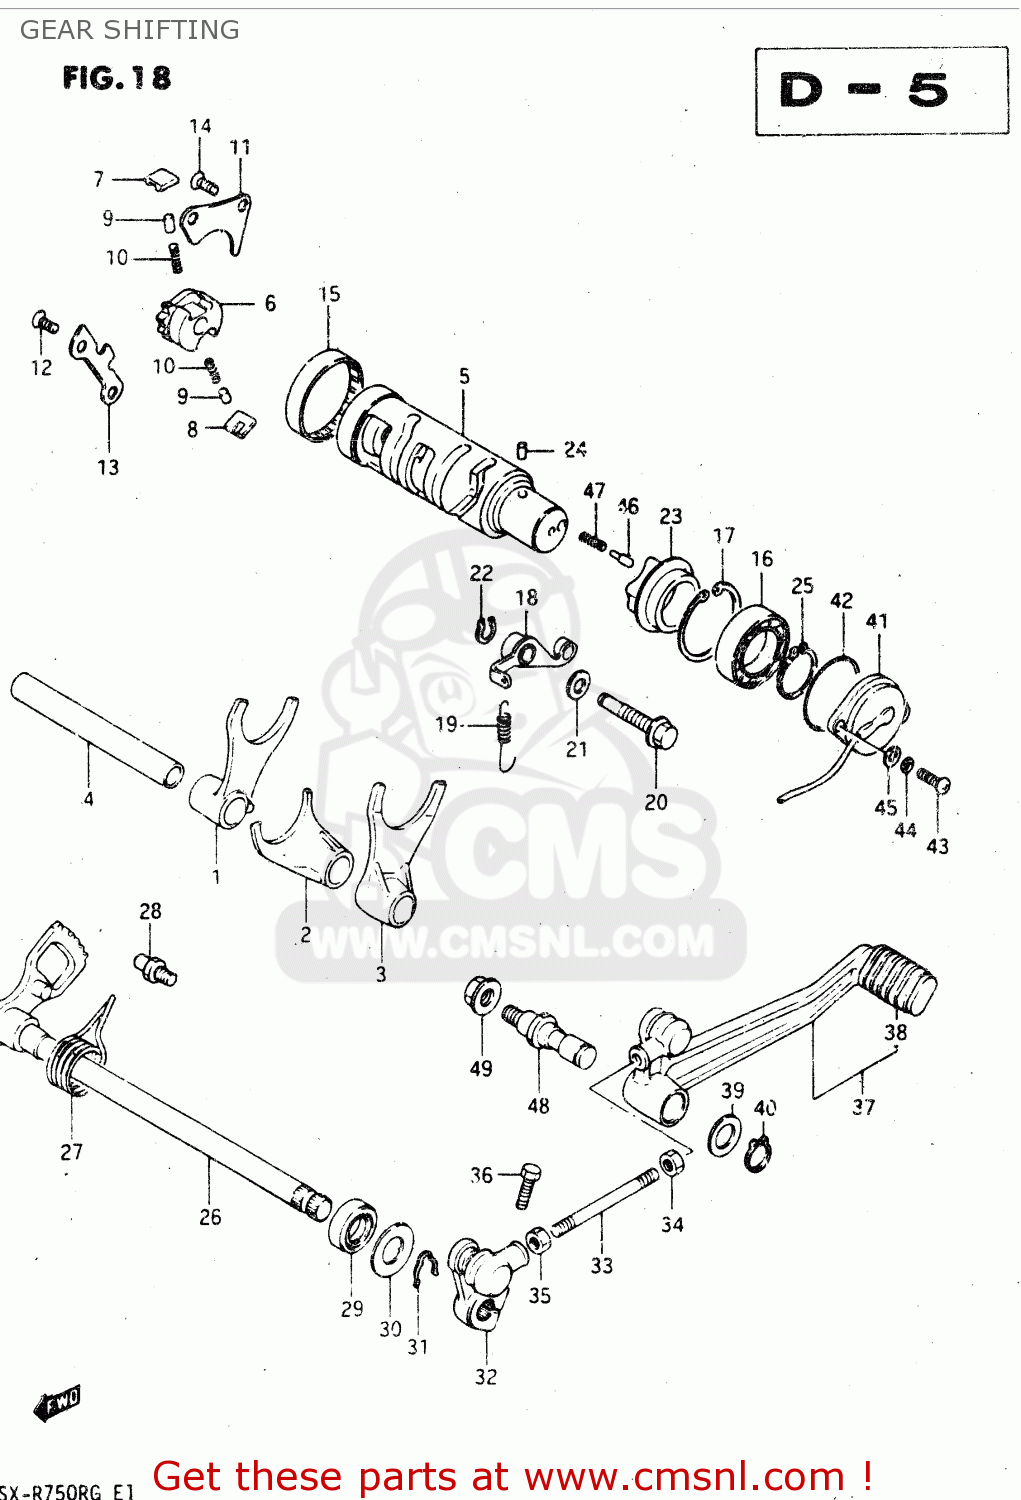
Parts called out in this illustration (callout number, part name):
1	FORK,GEAR SHIFT NO.1
2	FORK,GEAR SHIFT NO.2
3	FORK,GEAR SHIFT NO.3
4	SHAFT,GEAR SHIFT FORK(L:128)
5	CAM,GEAR SHIFT
6	GEAR,GEARSHIFT CAM DRIVE
7	PAWL,GEAR SHIFT NO.1
8	PAWL,GEAR SHIFT NO.2
9	PIN(5X8)
10	SPRING
11	LIFTER,GEAR SHIFT PAWL
12	SCREW
13	GUIDE,GEAR SHIFT CAM
14	SCREW
15	BEARING(43X49X12)
16	BALL BEARING
17	CIRCLIP,42MM
18	STOPPER,GEAR SHIFT CAM
19	SPRING
20	SHAFT,GEAR SHIFT CAM STOPPER
21	GASKET(10X14X3.6) (NAS)
22	CIRCLIP
23	PLATE,STOPPER
24	PIN 4X6
25	CIRCLIP,25MM
26	SHAFT,GEAR SHIFT
27	SPRING
28	STOPPER,GEAR SHIFT CAM
29	OIL SEAL
30	WASHER (12.5X27X1.6)
31	SPRING,RETAINER
32	ARM,GEAR SHIFT
33	ROD,GEAR SHIFT LINK
34	NUT
35	NUT 6MM
36	BOLT
37	LEVER ASSY,GEAR SHIFT
38	RUBBER,BRAKE PEDAL
39	WASHER(12.5X20X1)
40	CIRCLIP
41	TERMINAL BASE,NEUTRAL SWITCH
42	O RING(D:2.4,ID:36.5)
43	SCREW(5X14)
44	LOCK WASHER
45	WASHER
46	PIN(5X15.5)
47	SPRING
48	SHAFT,GEAR SHIFT LEVER
49	NUT
